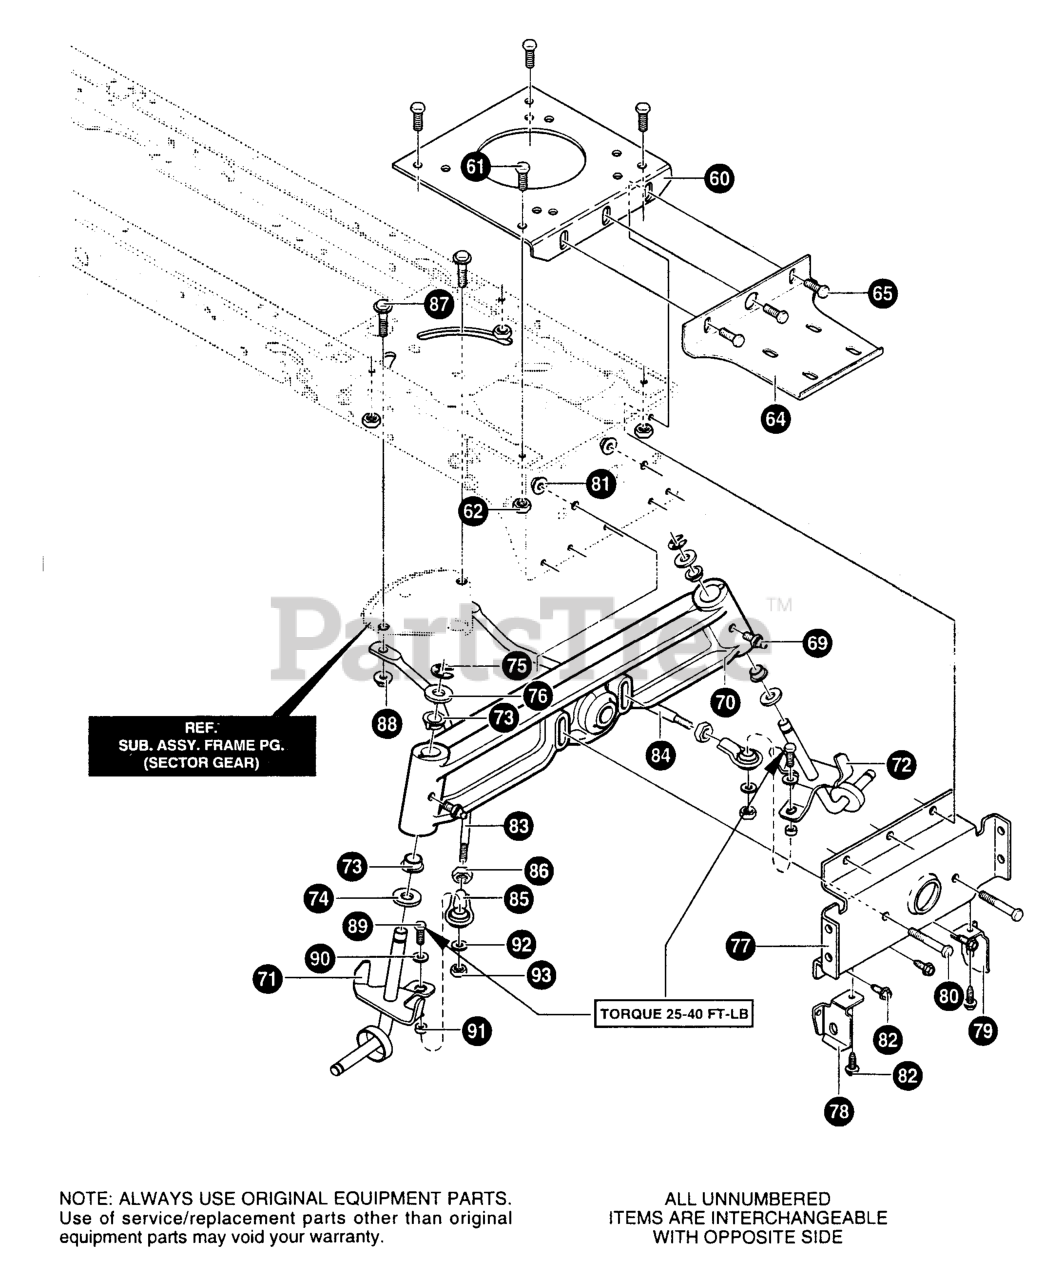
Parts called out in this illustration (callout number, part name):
60	PLATE, ENGINE
61	SCREW, 5/16-18 x .75 HHWATAP
62	NUT, 5/16-18 WDFLLK (15X88)
64	BRACKET, MUFFLER
65	SCREW, 5/16-18 x 0.75 HHWATAP
69	GREASE ZERK FITTING
70	AXLE, CAST IRON
71	SPINDLE, RH/STD. SPIN/NO BRG.
72	SPINDLE, LH/STD. SPIN/NO BRG.
73	BEARING, SPINDLE
74	WASHER, FLAT .766 x 1.62 ID
75	E-RING.574IDX.050/.750SH 11X3
76	WASHER, FLAT .765 x 1.81 x .059
77	HANGER, AXLE
78	HANGER, DECK RH
79	HANGER, DECK LH
80	Screw, 5/16-24 x 2.75
81	NUT, 5/16-24 NF-2 HEXFLLK
82	SCREW, 5/16-18 x .75 HHWATAP
83	ROD, DRGLNK/RH/ADJUST-5/8"
84	ROD, DRGLNK/LH/ADJUST-5/8"
85	TIE ROD END 1/2-20
86	NUT, 1/2-20 HXJAM
87	BOLT, HHSH (9X57)
88	NUT, 3/8-16 HWDFLLK MACK 15X84
89	BOLT, .500X1.18 HHSH 3/8-16
90	WASHER, FLAT .515X1.37X.119
91	SPACER, SLEEVE.515X.70X.
92	FLATWASHER .378X.75X.08
93	NUT, 3/8-16 REGHXCTRLK
